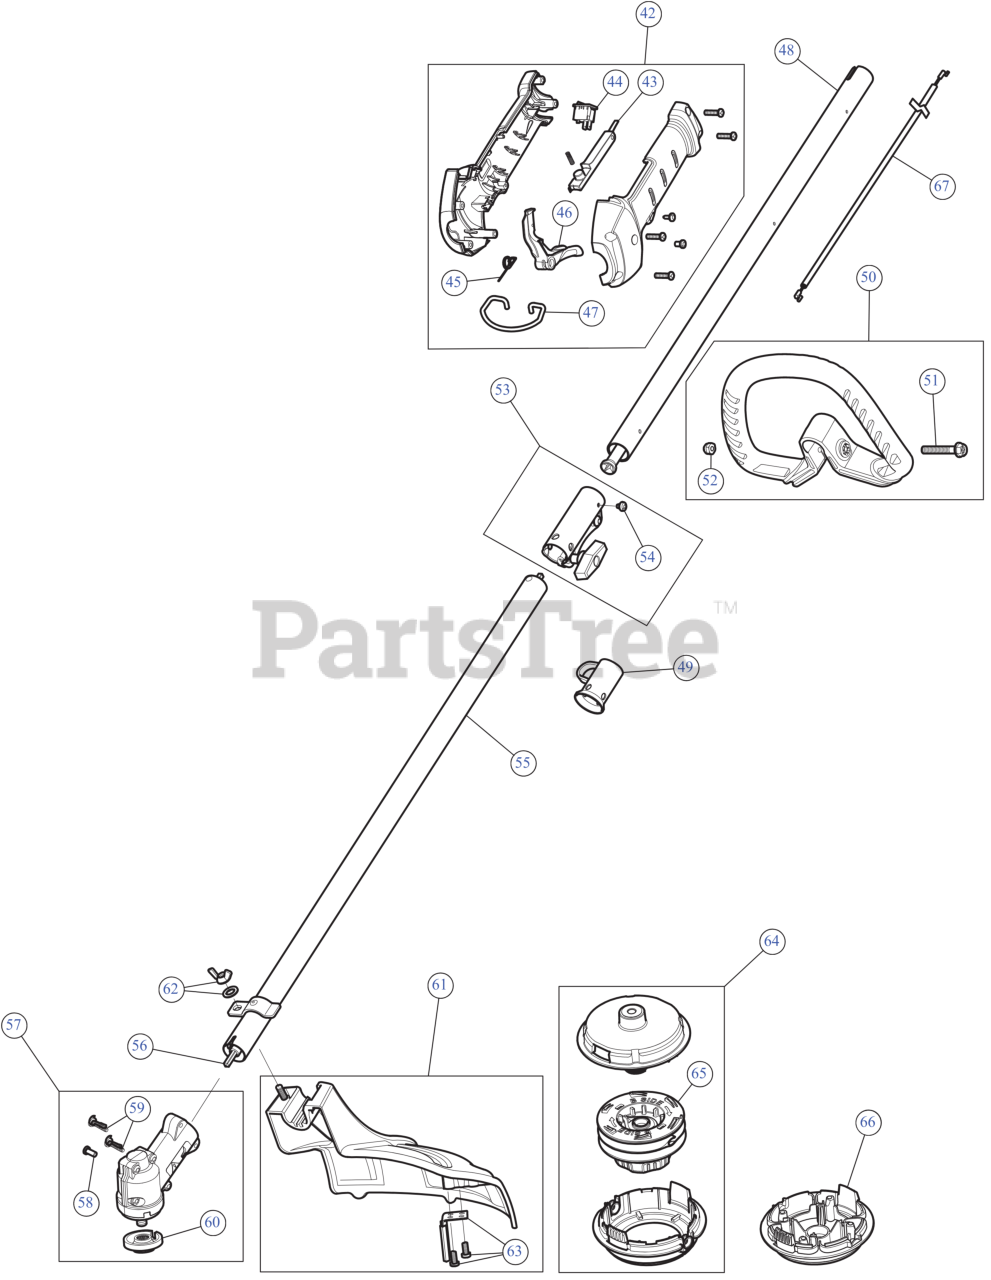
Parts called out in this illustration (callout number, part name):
42	THROTTLE GRIP ASM
43	LEVER LOCK OUT
44	SW, MOMENTARY ON/O
45	SPRING TRIG
46	THROTTLE TRIGGER
47	SHOULDER STRAP CLIP
48	UPPER BOOM ASSEMBLY
49	HANGER
50	HANDLE ASSEMBLY
51	BOLT 1/4-20X1 1/2
52	NUT 1/4-20 NYLOC
53	COUPLER ASSEMBLY
54	SCREW, 10-32X.250 TA
55	LOWER BOOM ASSEMBLY
56	LOWER DRIVE SHAFT
57	GEARBOX LCBC
58	SCREW, 8-32 x .312 P
59	SCREW #
60	CUTTING HEAD SPACER
61	GUARD/BLADE ASSEMBLY
62	BLADE GUARD MOUNTING HARDWARE
63	BLADE ASSEMBLY W/HDW
64	COMPLETE HEAD ASSEMBLY
65	BUMP KNOB
66	CAP ASSEMBLY W/PLUG
67	THROTTLE CABLE
